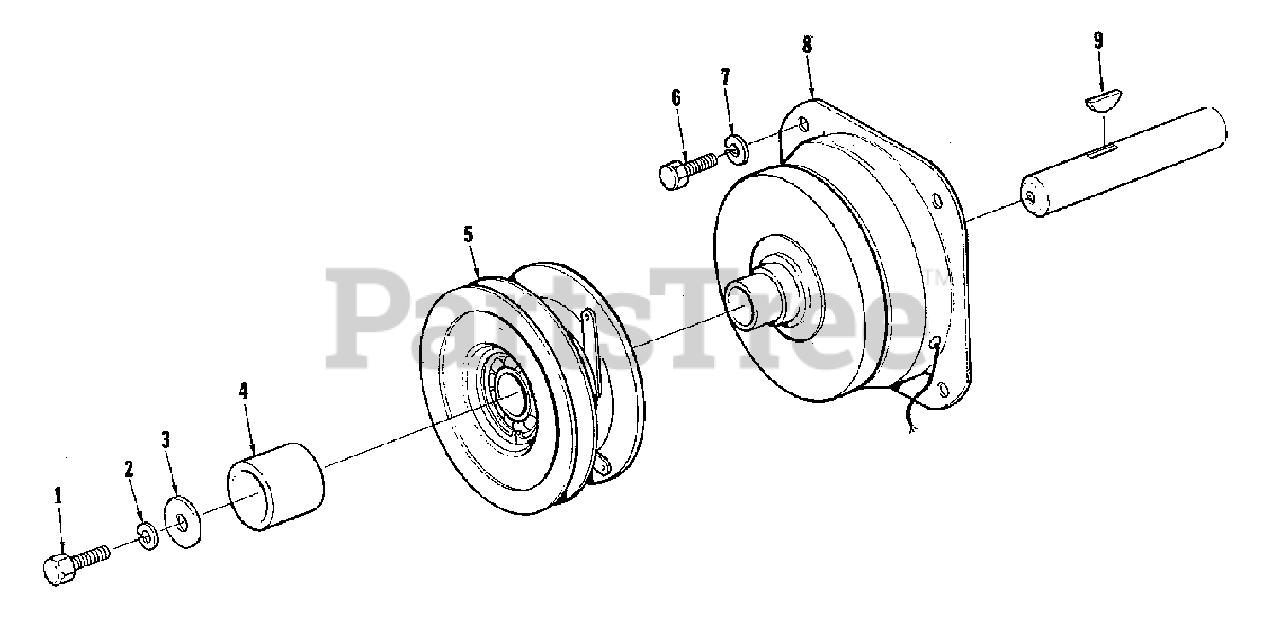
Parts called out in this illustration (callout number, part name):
1	SCREW, Hex Head Cap, 3/8-24 x 1-1/8
2	WASHER, Lock, 3/8
3	WASHER, Flat
5	COIL ASSEMBLY, PTO Clutch
6	SCREW, Hex Head Cap, 7/16-14 x 5/8
7	WASHER, Lock, 7/16
8	HUB ASSEMBLY, PTO Clutch
9	KEY, Plain Parallel
